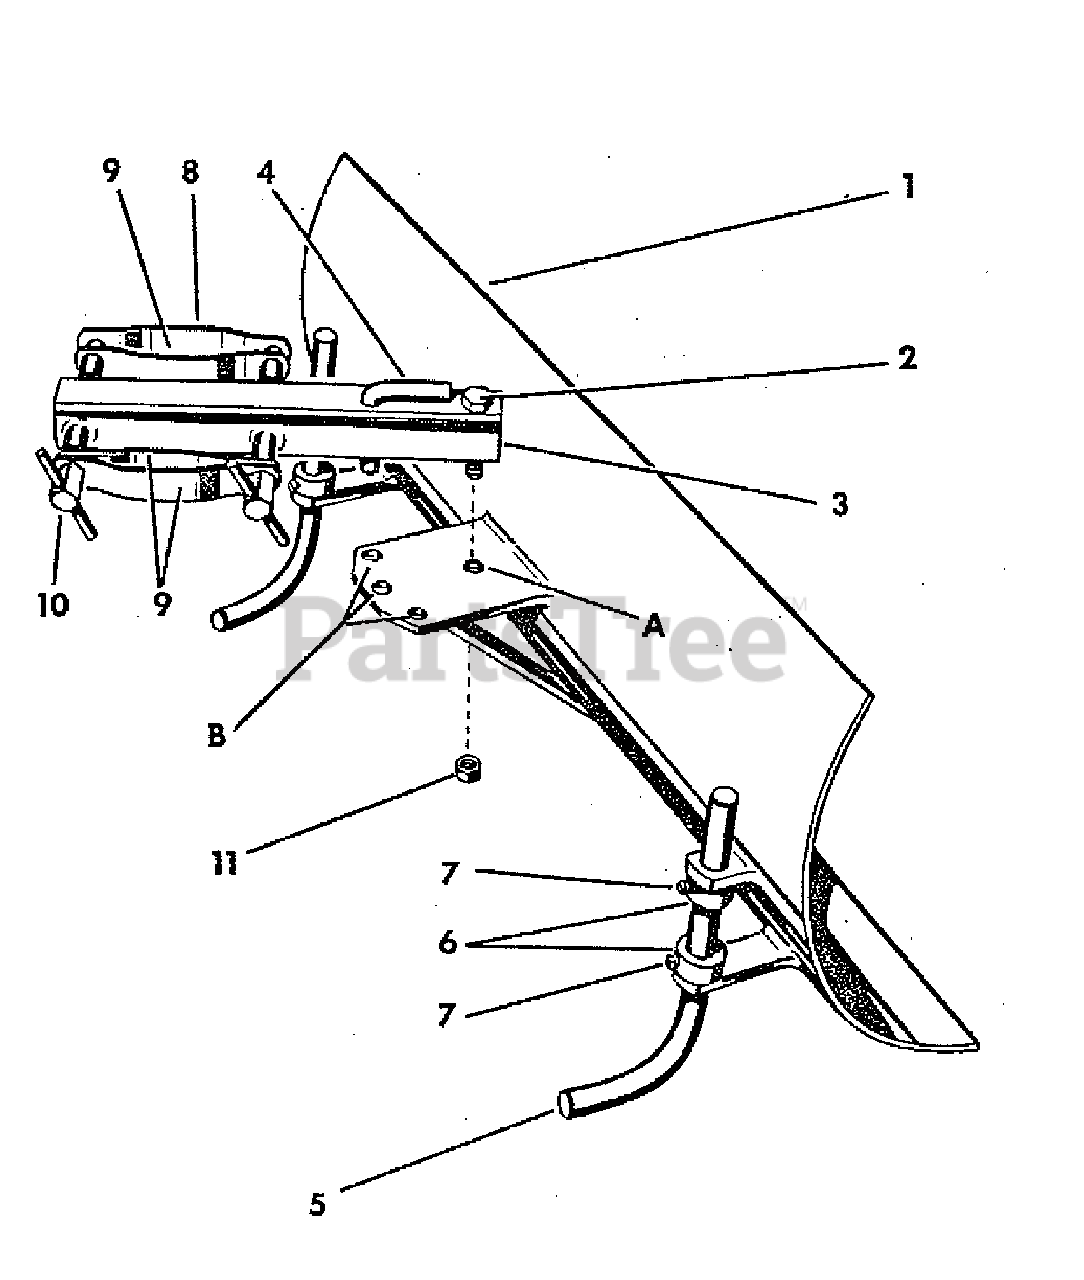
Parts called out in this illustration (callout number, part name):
1	BLADE ASSEMBLY
3	PUSH BAR ASSEMBLY
4	PIN, Pivot
6	COLLAR, Set
8	CLAMP, Hitch
9	SIDE PLATE, Hitch
10	NUT, Complete, Wing
